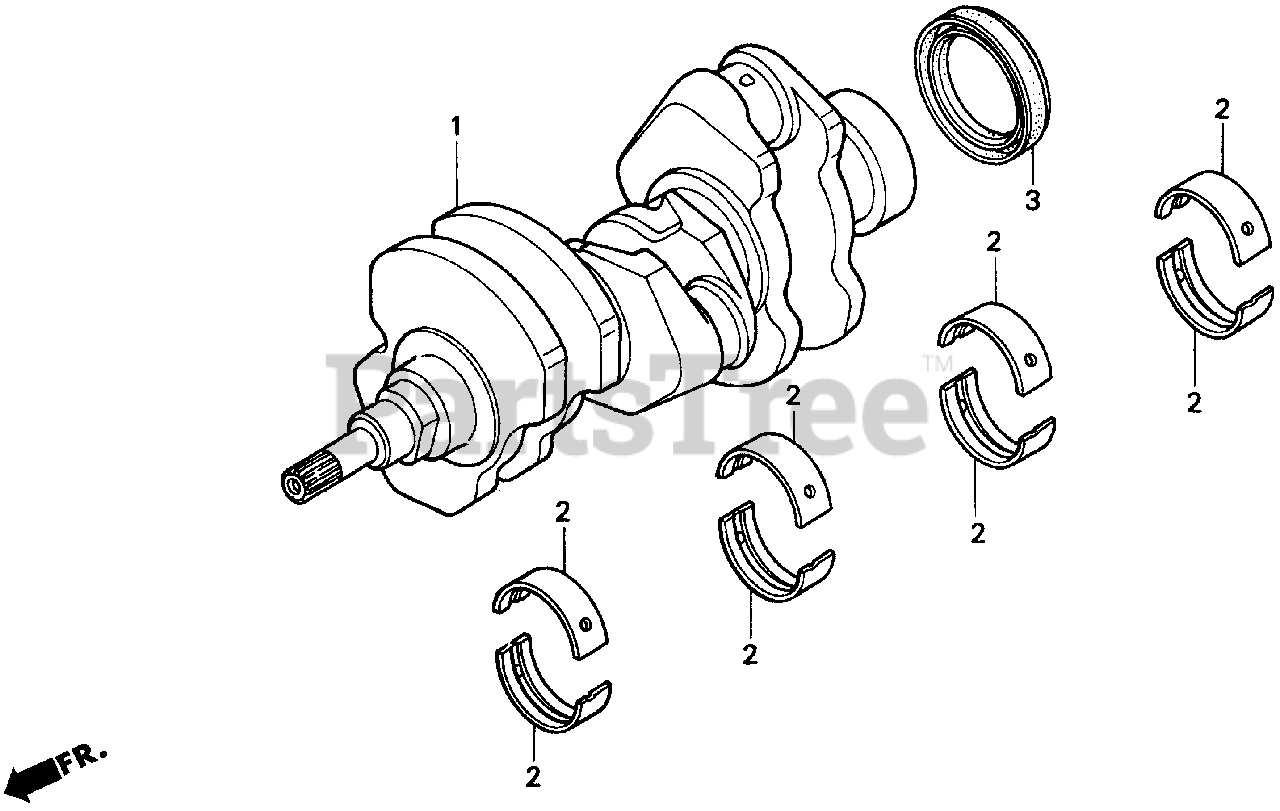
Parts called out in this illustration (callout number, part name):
1	CRANKSHAFT
2	BEARING A, MAIN (BLUE)
2	BEARING B, MAIN (BLACK)
2	BEARING C, MAIN (BROWN)
2	BEARING D, MAIN (GREEN)
2	BEARING E, MAIN (YELLOW)
2	BEARING F, MAIN (PINK)
2	BEARING G, MAIN (RED)
3	OIL SEAL (72X92X9)
